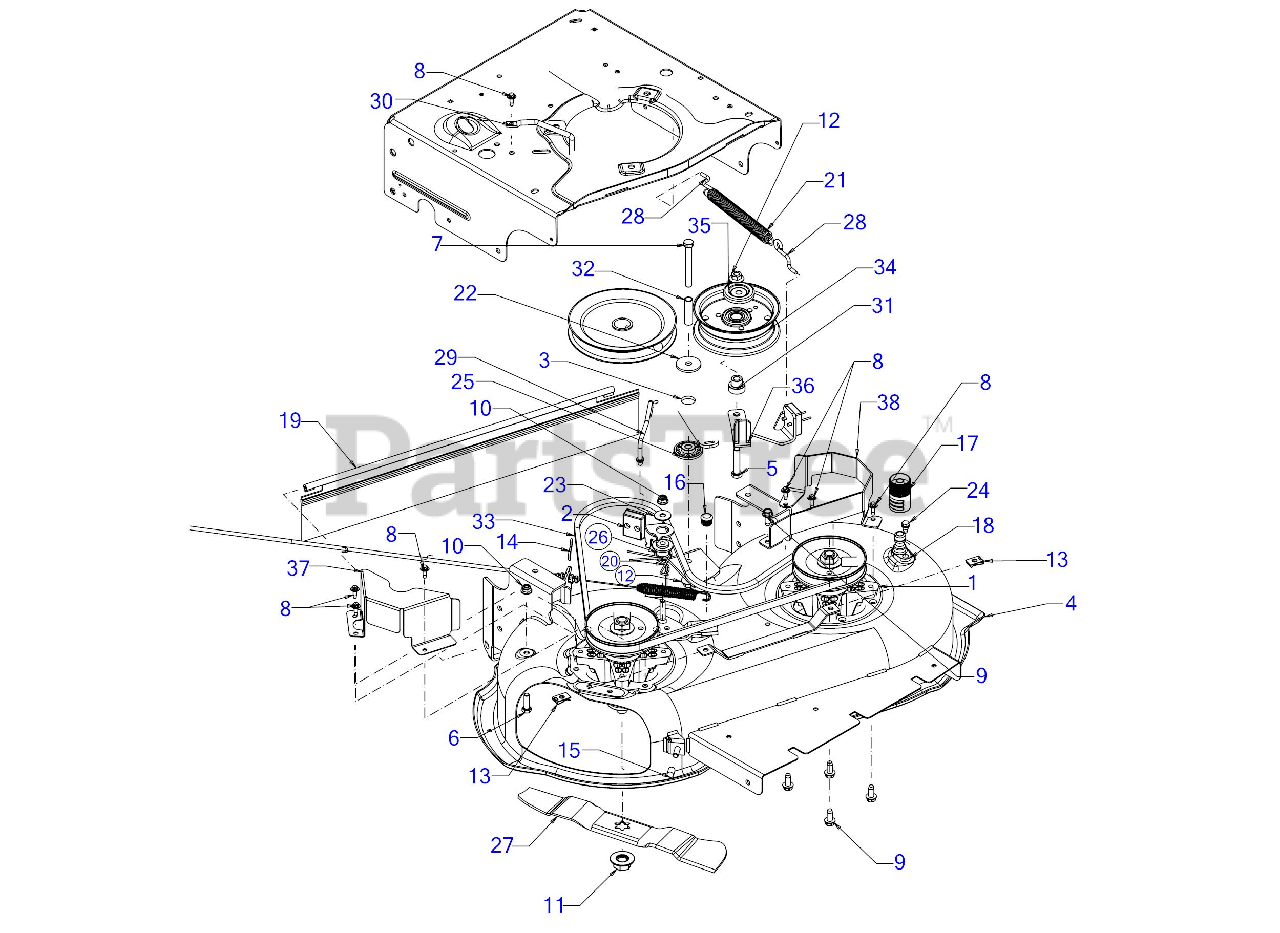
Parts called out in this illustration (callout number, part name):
1	SPINDLE ASM 4.6" DIA
2	DECK BRAKE ASSEMBLY
3	IDLER PIVOT ASSEMBLY BRACKET
5	HEX SCREW 3/8-16 x 1.75 GR5
6	SCREW 5/16-18 x 1.0 GR5
7	SCREW 3/8-16 x 3 GR8
8	SCREW M6-1 x .625
9	SCREW 5/16-18 x .750
10	FLANGE LOCK NUT 5/16-18
12	FLANGE LOCK NUT
13	U NUT M6-1
14	PIN:COTTER
16	HANDLE PLUG
17	WATER NOZZLE
18	DECK WASH NOZZLE
19	23.25" TRAIL SHIELD
20	TORSION SPRING
21	EXTENSION SPRING (.750 DIA x 6.70 )
22	FLAT WASHER .390x1.500x.134
23	FLAT WASHER 344X1.00
24	SHOULDER SCREW 1/4-20 x .50
25	SHOULDER SPACER
26	DOUBLE SHOULDER SPACER .750 X .135
27	14.20" BLADE (MULCH)
27	Cub Cadet 28" BLADE SET
27	Genuine Factory Parts 28" BLADE SET
27	BLADE (HI LIFT) (14.2)
29	DECK BRAKE ROD
30	ENGINE PULLEY BELT KEEPER ROD
31	SHOULDER SPACER
33	V-BELT A SEC x 60.0
34	IDLER PULLEY 4.50" DIA
35	IDLER PULLEY CAP
